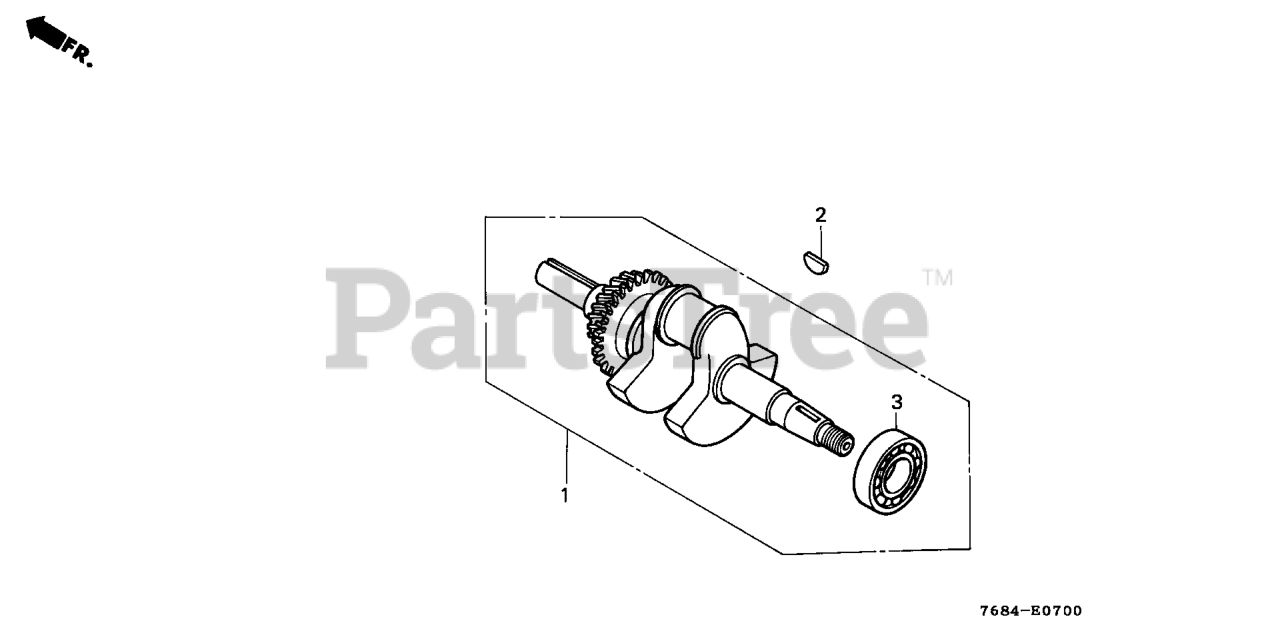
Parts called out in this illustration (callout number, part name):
1	CRANKSHAFT
2	KEY, SPECIAL WOODRUFF (25X18)
3	BEARING, RADIAL BALL (6206)
